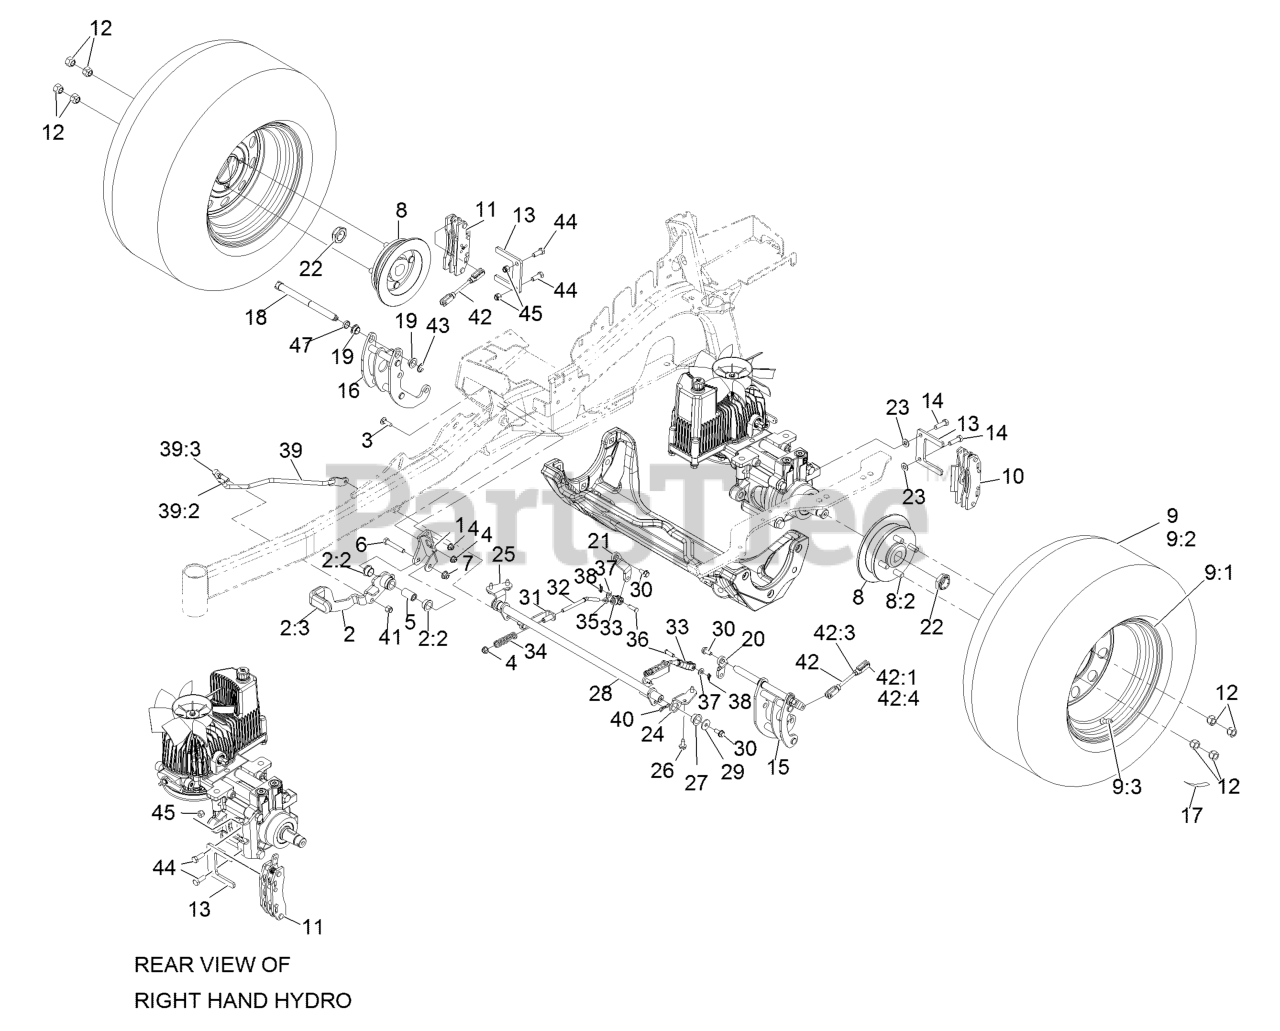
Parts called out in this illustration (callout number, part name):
1	BRACKET-MOUNT
2	BRAKE LEVER ASM W/ GRIP
2:2	BUSHING-FLANGE
2:3	Grip-Lever
3	BOLT-CARR
4	NUT-HF, NI
5	HANDLE-PIVOT, BRAKE
6	SCREW-HH
7	NUT-HF, NI
8	WHEEL HUB ASM
8:2	STUD-WHEEL
9	ASM-WHEEL AND TIRE
9:1	ASM-RIM 60
9:2	TIRE-DRIVE
9:3	Stem-Valve
10	CALIPER-BRAKE
11	CALIPER-BRAKE, RH
12	NUT-LUG
13	PLATE-MOUNT, BRAKE
14	SCREW-LOCK, PATCH
17	DECAL-TORQUE, WHEEL HUB LUG
18	BELLCRANK
19	BUSHING
20	ARM-INNER, LH
21	ARM-INNER, RH
22	LOCKNUT
23	WASHER-FLAT
24	MOUNT-PIVOT, LH
25	MOUNT-PIVOT, RH
26	Screw-HWH 5/16-18 X 3/4 Tf
27	BUSHING-FLANGE
28	SHAFT-CROSS
29	WASHER-FLAT
30	SCREW-HHF
31	BRACKET-L
32	LINKAGE-MID
33	YOKE-OFFSET
34	SPRING-COMPRESSION
35	NUT-JAM
36	PIN-CLEVIS
37	WASHER-PLAIN
38	PIN-COTTER, LOCKING
39	FRONT LINKAGE ASM
39:2	END-TIE ROD, RH
39:3	NUT-HJ
40	PIN-COTTER, LOCKING
41	NUT-LOCK
42	REAR LINKAGE ASM
42:3	NUT-JAM
42:4	PIN-CLEVIS, SPRING
44	SCREW-HH
45	NUT-LOCK, NI
